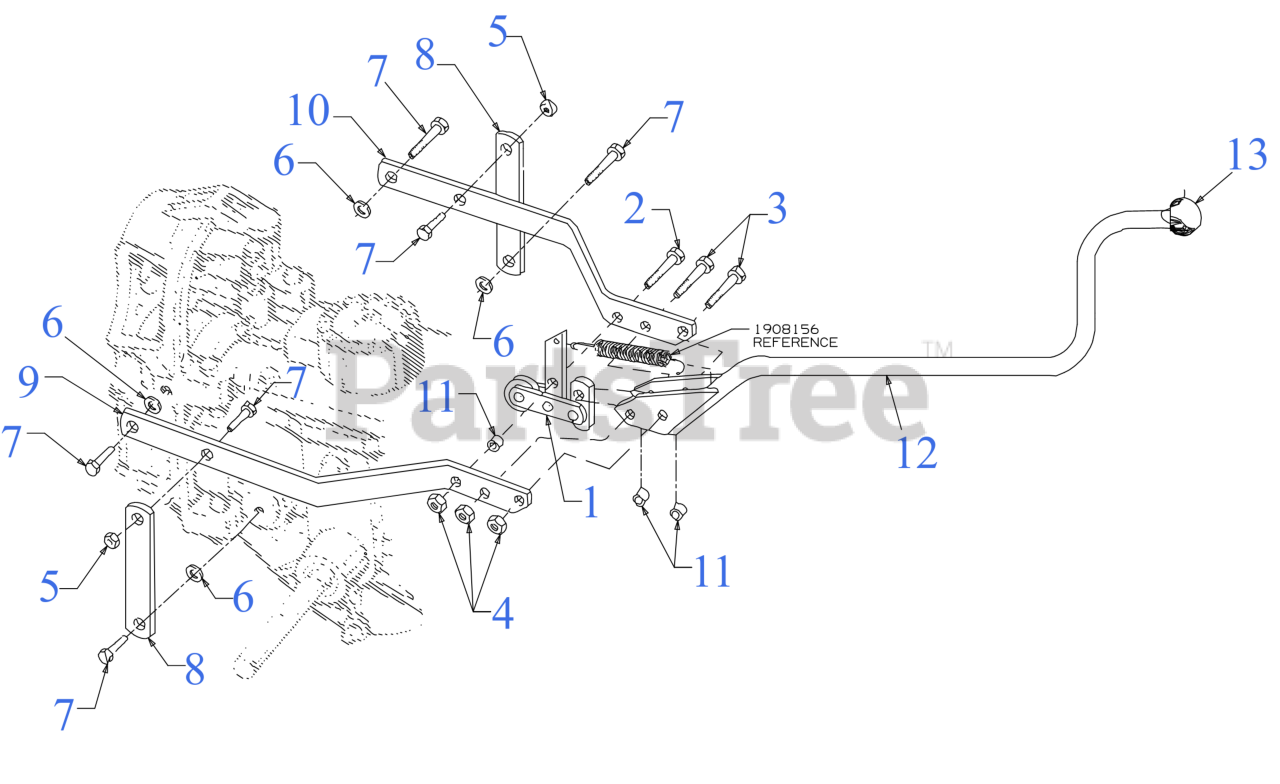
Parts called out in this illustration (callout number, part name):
1	ROLLER REPAIR KIT
2	SCREW 5/16-18 x 1.5 LG
3	SCREW 5/16-18 x 1.75 GR5
4	FLANGE LOCK NUT 5/16-18
5	LOCK NUT 3/8-16
6	BELL WASHER .390x1.130x.062
7	SHOULDER SCREW .498 DIA x .340
8	CLUTCH YOKE BAR
9	YOKE (LH) RED
11	BUSHING .5 x .316 x .375
12	FORWARD/REVERSE LEVER ASSEMBLY
13	KNOB W/INLAY-FWD/R
